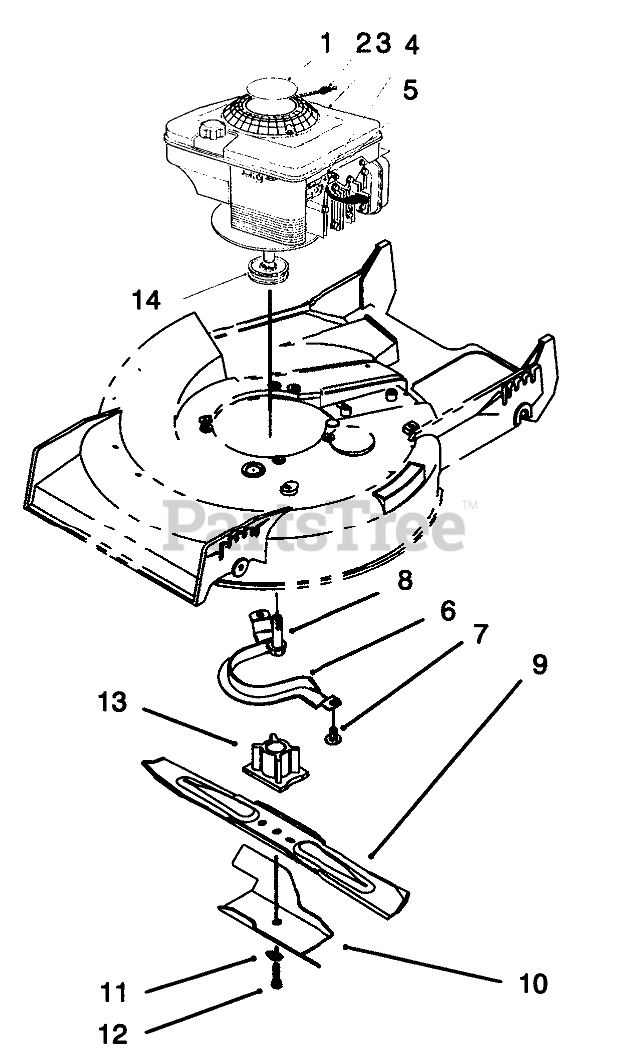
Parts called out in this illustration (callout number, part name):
1	DECAL-ENG F/W ENGINE
2	STOP-ROPE
4	CLAMP-CASING
5	Screw
6	Guide-Belt
7	SCREW-HWHTF
8	SCREW-HWH
9	Blade
10	Accelerator
11	WASHER-LOCK
12	SCREW-BLADE
13	BLADE RETAINER
14	PULLEY-DRIVE, ZONE START
